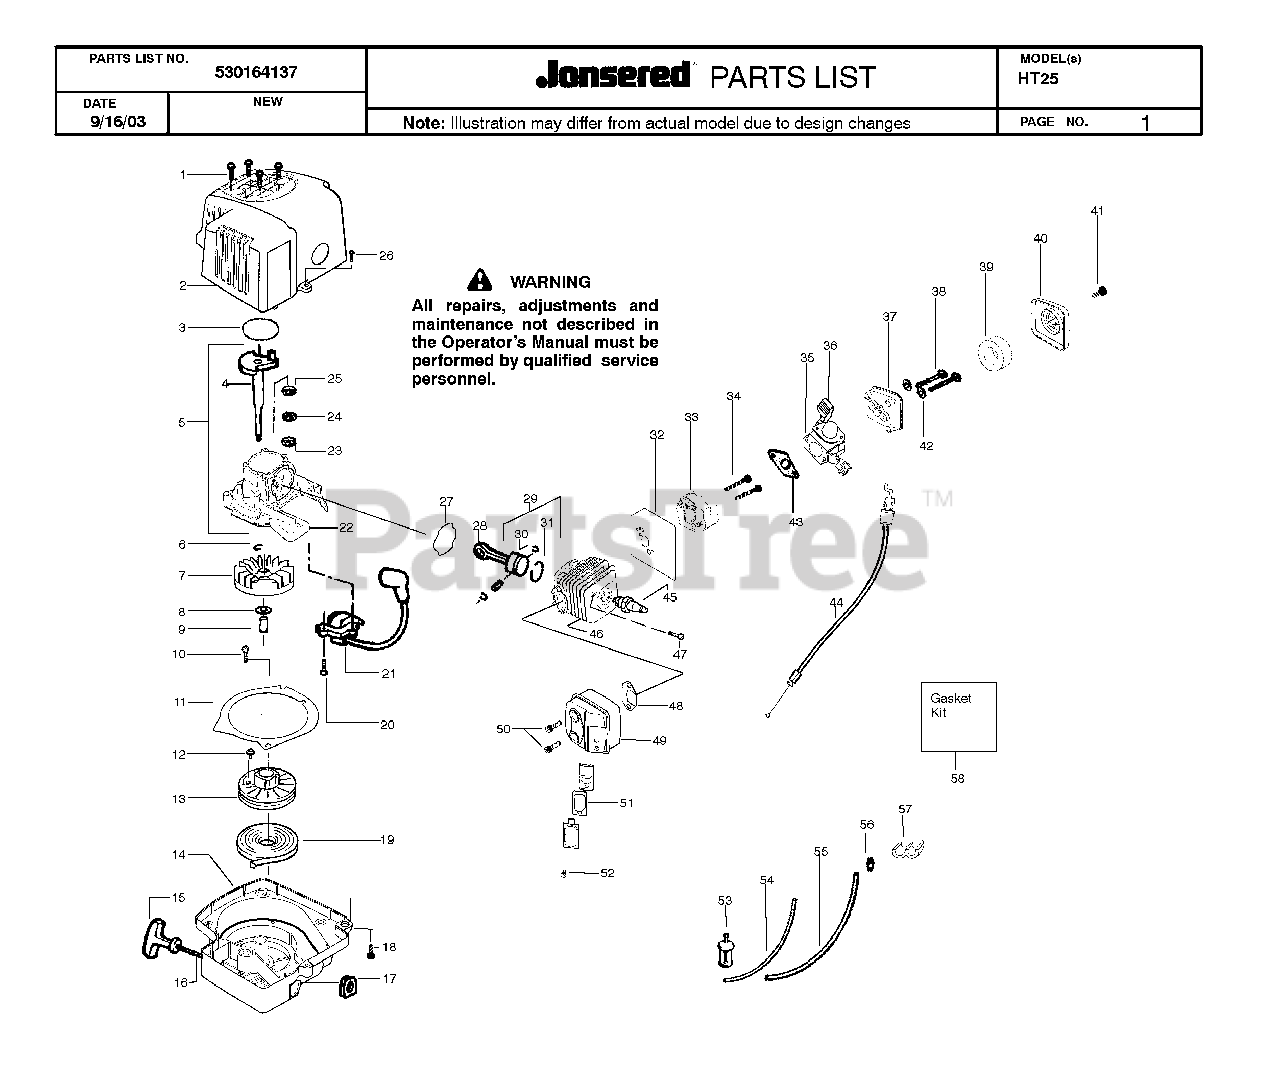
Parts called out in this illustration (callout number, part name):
2	ASSY-SHROUD
3	GASKET KIT
4	CRANKSHAFT
5	CRANKCASE
6	RETAINING RING
7	FLYWHEEL
8	WASHER FLAT
10	SCREW-10-16 X 1/2 HI-LO
11	PLATE-BAFFLE
12	SCREW SEMS TOOTHED WASHER
13	STARTER PULLEY
14	FAN HOUSING
15	HANDLE-STARTER
19	STARTER SPRING
21	IGNITION MODULE
22	CRANKCASE
23	OUTER BEARING
25	BEARING
27	GASKET KIT
29	PISTON
30	WRIST PIN RET.
31	PISTON RING
32	GASKET KIT
40	AIR FILTER COVER
42	WASHER
43	GASKET KIT
44	THROTTLE WIRE
45	PLUG-SPARK (RCJ-6Y)
48	GASKET KIT
50	SCREW MUFFLER
51	PARTITION
52	SCREW-6-19X5/16PLAST PA
53	ASSY-FUEL PICK-UP
56	FUEL LINE FITTING
58	GASKET KIT
